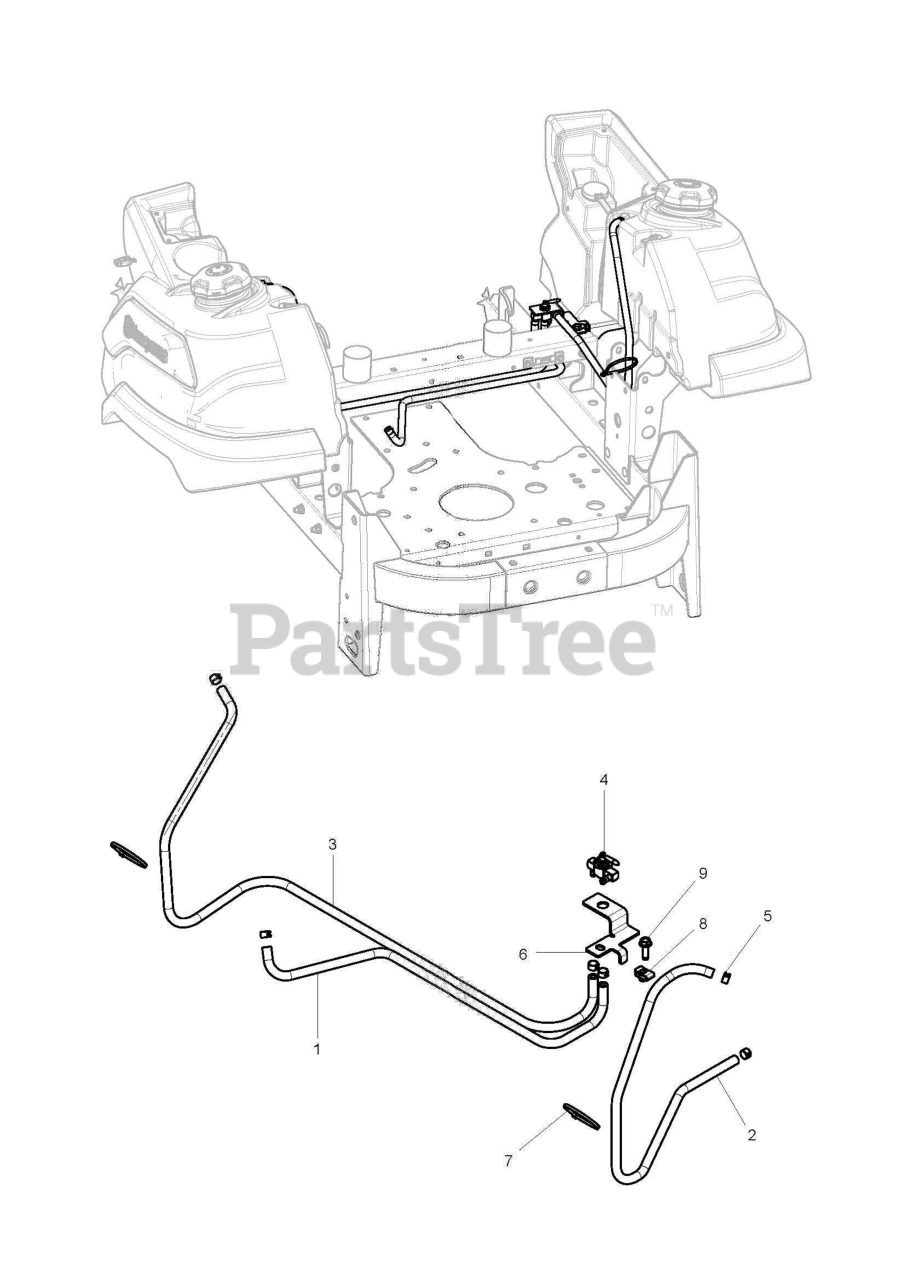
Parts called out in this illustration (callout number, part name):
1	HOSE 1/4" LOW PERMEATION FUEL
2	HOSE.1/4".LOW.PERM.FUEL.LN.33"
3	HOSE.1/4".LOW.PERM.FUEL.LN.54"
5	CLAMP, HOSE
7	TIE, PLASTIC
8	U-CLIP 5/16-18 NUT RETAINER
9	SCREW HEX HEAD W/ WASHER 5/16-
